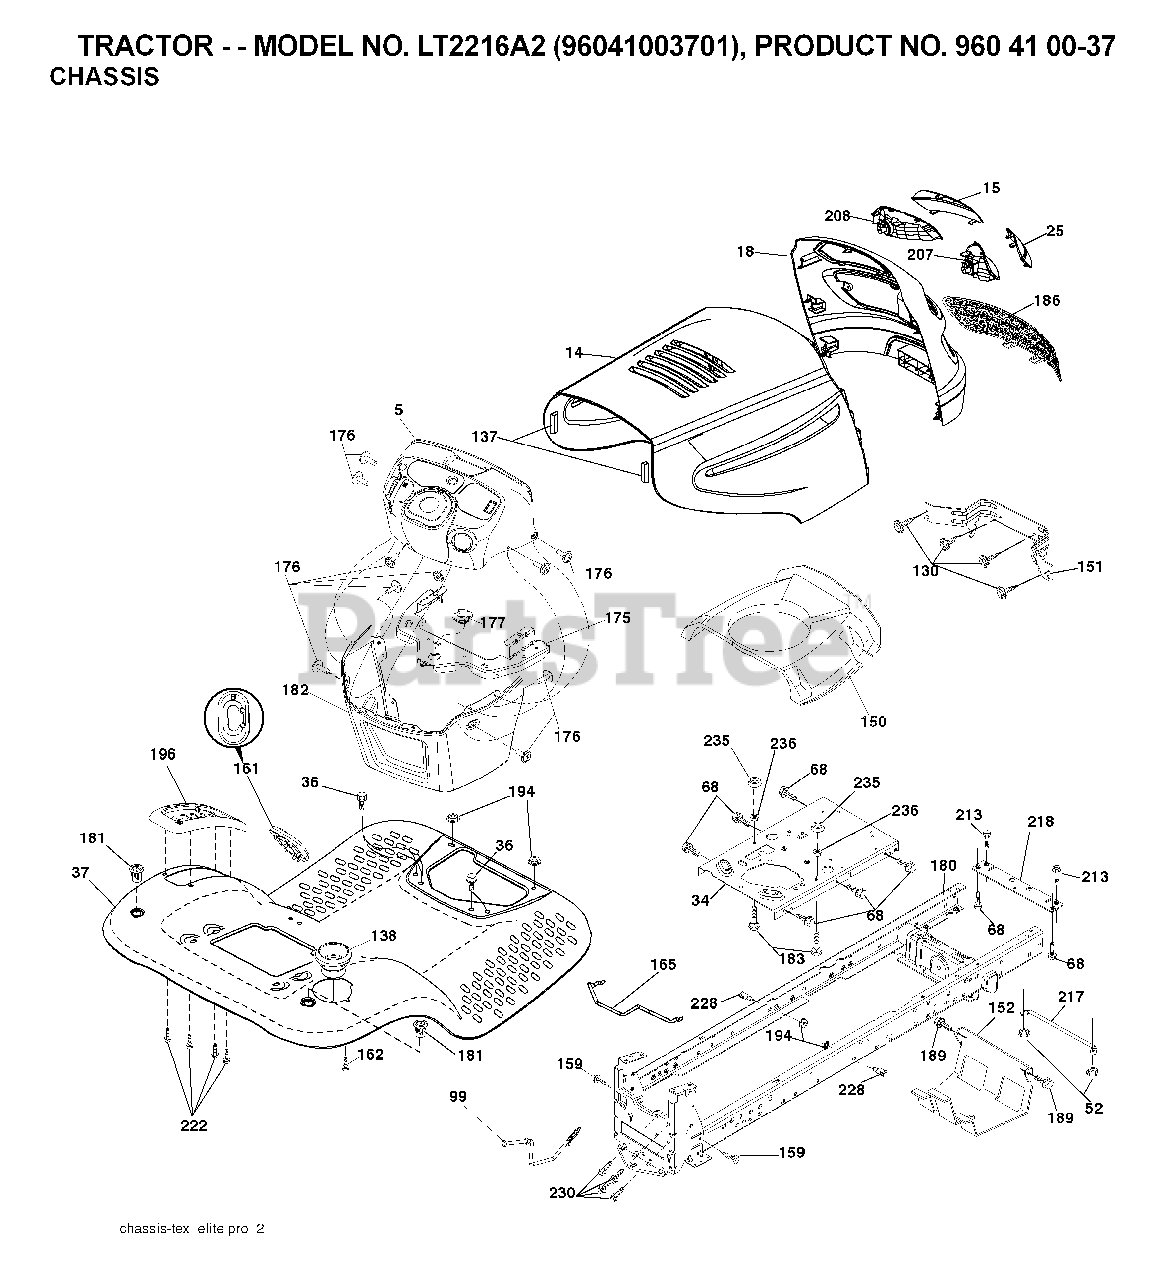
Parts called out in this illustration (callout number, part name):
34	PLATE.ENGINE.WELDED.CHASSIS
36	SCREW 5/16"
52	LOCKNUT
99	ROD.ASM.BYPASS.0510.HYDRO.LT
130	SCREW
137	BUMPER.HOOD.LARGE.1.75"
138	CUPHOLDER.TL.TEX.BLACK
151	BRACKET PIVOT
152	SHIELD BROWNING
159	SCREW, 3/8-16X3/4
161	WINDOW.FUEL.LT.TEX.BLACK
162	SCREW.HI-LO.CONSOLE
165	SUPPORT.TANK.REAR.W/TE
175	CROSSMEMBER.LT
176	SCREW.#10-24X5/8.RN.QU
177	BUSHING STEERING
180	CHASSIS
181	FEND/FTRST.PCH.CPH.NFW
182	DASH.LOWER.LT.CCS
183	BOLT.5/16-18X1-1/4 FULL.THREAD
189	SCREW
194	NUT LOCK HEX FLANGE 5/16-18
196	CONSOLE.ASM.DECK.LIFT.TLT.BLAC
207	BEZEL GRILL RH
208	BEZEL GRILL LH
213	BOLT
217	ROD.PIVOT.HOOD
218	X-PIECE.HOOD.STOP.NON/
222	SCREW.1/4-20X5/8
228	STUD.FASTNER.W/ANTI-ROTATE
230	SHOULDER BOLT 5/16-18TT
235	SPACER FENDER
236	NUT.CENTERLOCK.5/16-
